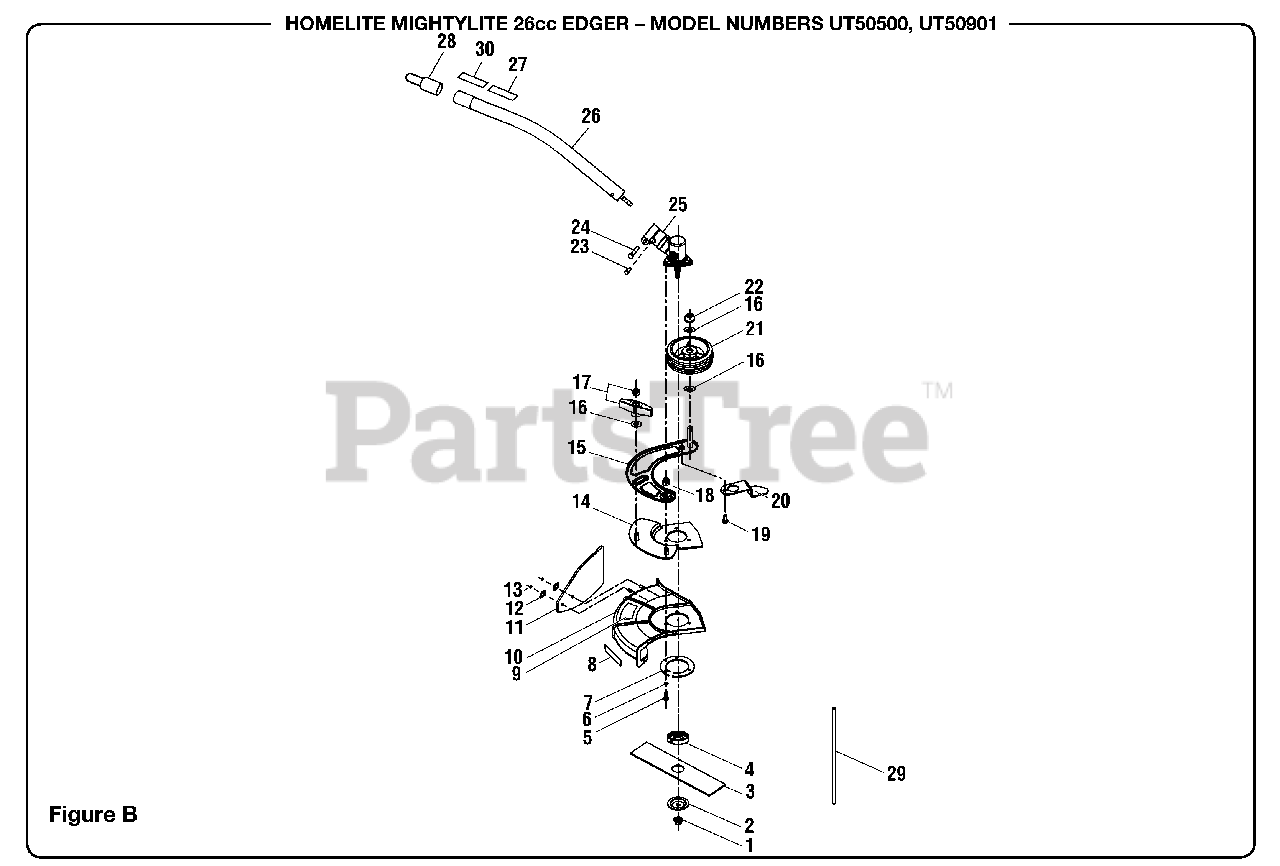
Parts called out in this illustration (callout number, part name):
1	Blade Nut (M8)
2	Cupped Washer
4	Flange Washer
5	Screw (10-24 x 5/8 in Hex Hd.)
6	Lock Washer (5 mm)
7	Flange
8	Warning Decal
9	Logo Label
10	Blade Guard
11	Debris Flap
12	Washer (6 mm)
13	Hex Nut (10-24)
14	Plate with Stud
15	Wheel Arm
16	Washer (10 mm)
17	Adjusting Knob with Hex Nut
18	Hex Nut with Nylon Cap (5/16-18)
19	Hex Screw (10-24 x 1/2 in.)
20	Curb Guide
21	Guide Wheel
22	Push Nut (10 mm)
23	Hex Screw (10-24 x 5/8 in.)
24	Cap Screw (1/4-20 x 1.25 in.)
25	Gear Head Assembly
26	Drive Shaft Assembly
27	Warning Label
28	Hanger Cap
29	Holding Pin
30	Expand-It Label
